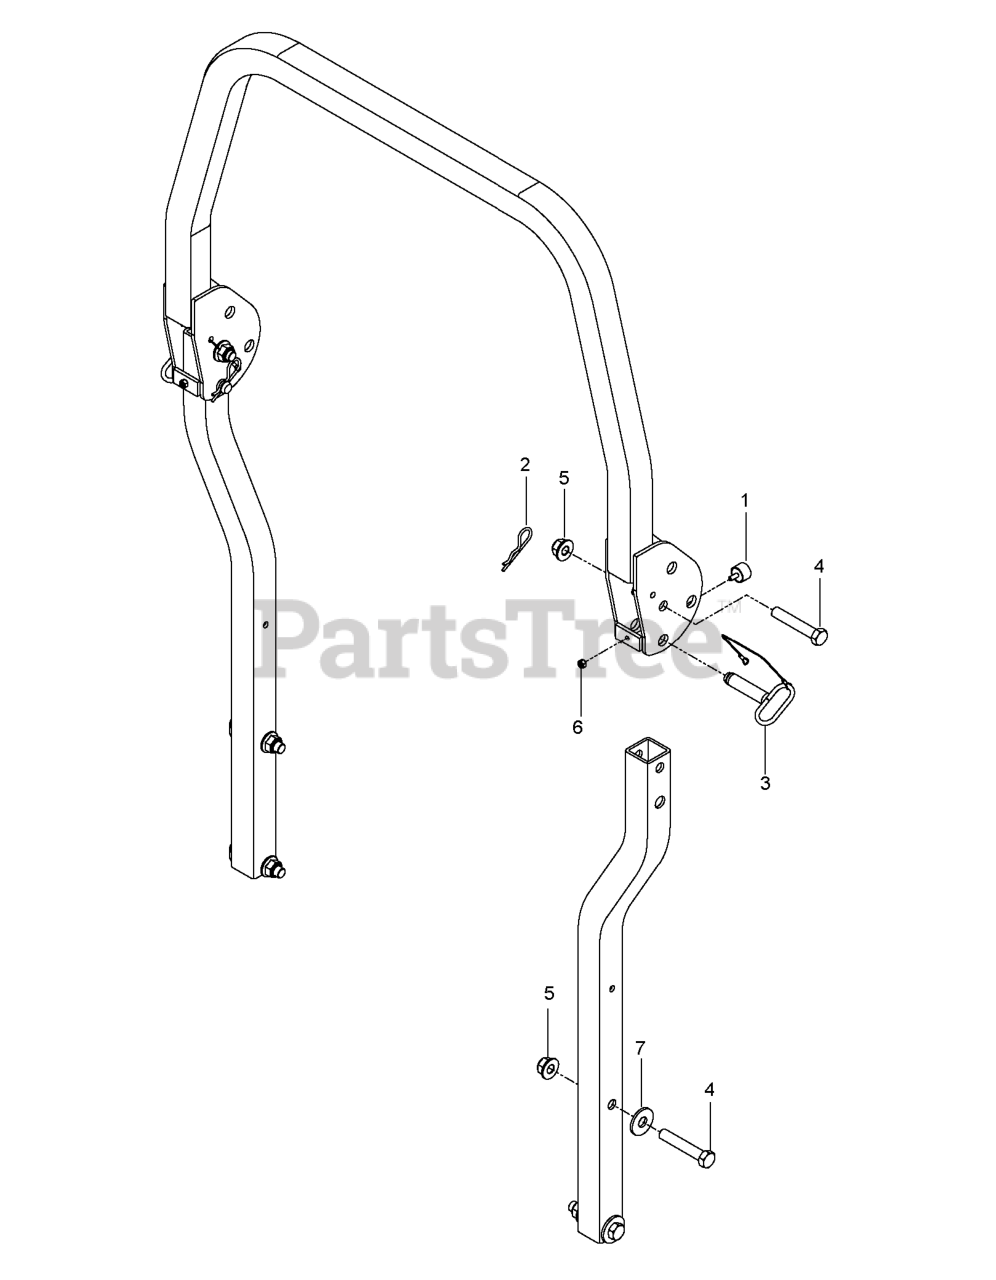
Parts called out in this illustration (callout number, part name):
1	BUMPER, MALE STUD, 1/4-20
2	PIN HAIR .148 X 2-15/16 #210
3	PIN, ROPS
4	5/8-11 X 3-1/2 HHB GRADE 5
5	NUT 5/8-11 FLG NYLOC ZD
6	NUT.1/4-20.HEX.NYLOC.ZD
7	WASHER, 5/8 FLAT
